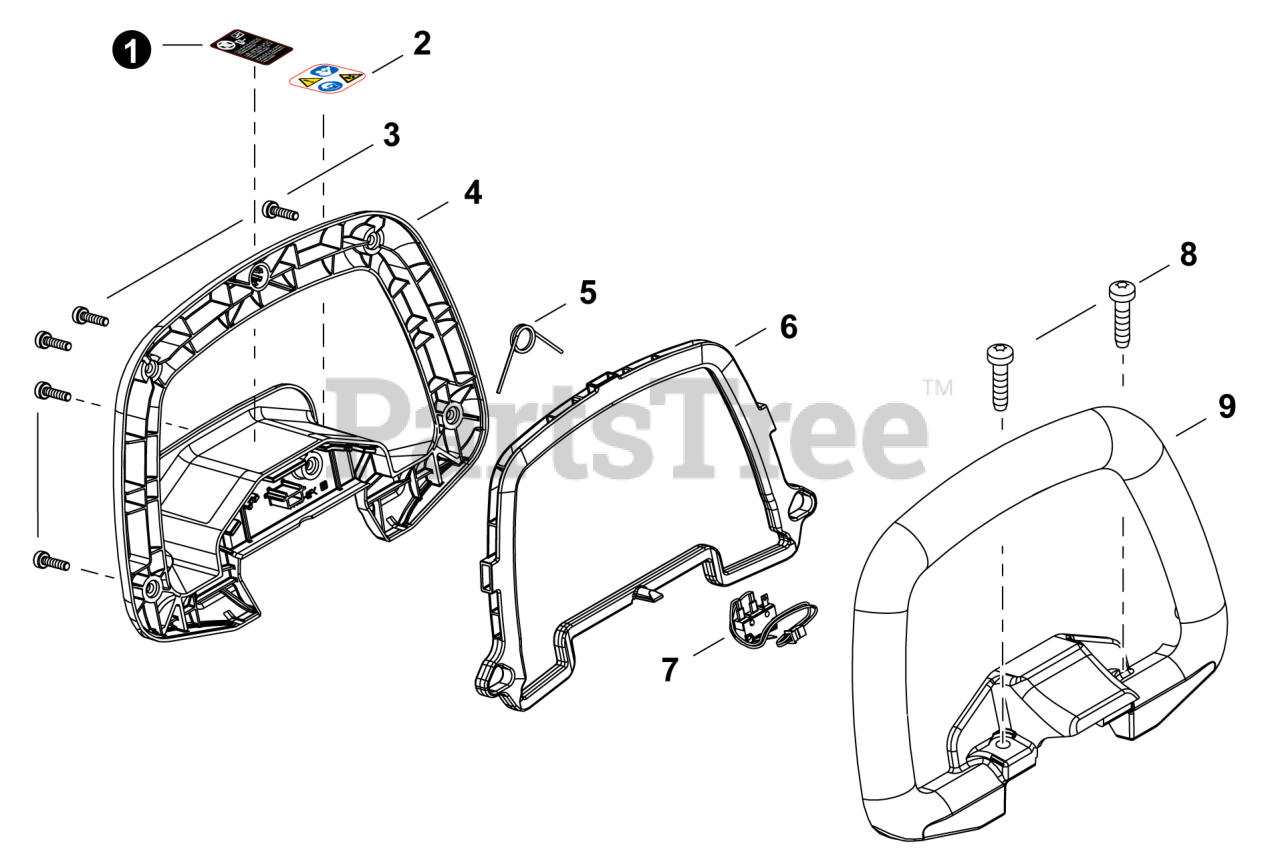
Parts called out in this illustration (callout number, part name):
1	LABEL - CAUTION - UL
2	LABEL - CAUTION - ISO
3	BOLT, TORX 4x16
4	HANDLE, SUPPORT - REAR
5	SPRING, TORSION
7	HARNESS, WIRE
8	BOLT, TORX 6x30
9	HANDLE, SUPPORT - FRONT
